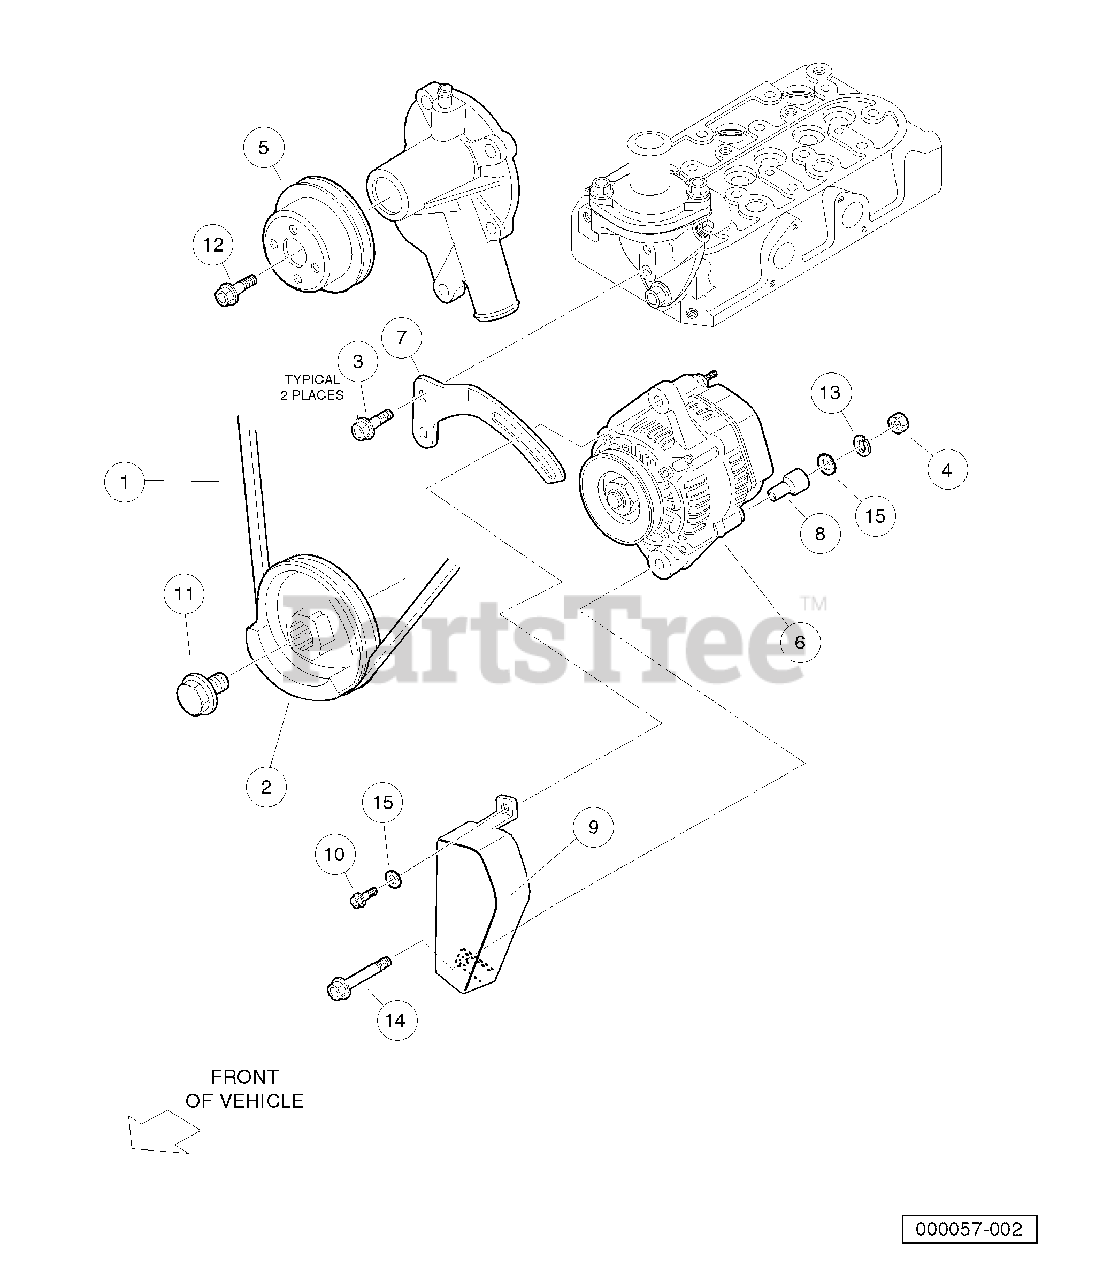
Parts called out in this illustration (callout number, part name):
2	Pulley, Fan Drive
3	Bolt, M6 X 1 X 20
4	Nut, M8, Plate
5	Pulley, Water Pump
6	Alternator, 40-Amp
7	Stay, Alternator Assy, D722
8	Collar, Alternator Assy, D722
9	Cover, Alternator Assy, D722
10	Bolt, Alt, D722, Adjuster
11	Bolt, Alt, D722, Drive Pulley
12	Bolt, D722, Drive Pulley
13	Washer, Spring, D722, Starter
14	Bolt, Alternator, Lower
15	Washer, Alternator, Upper
